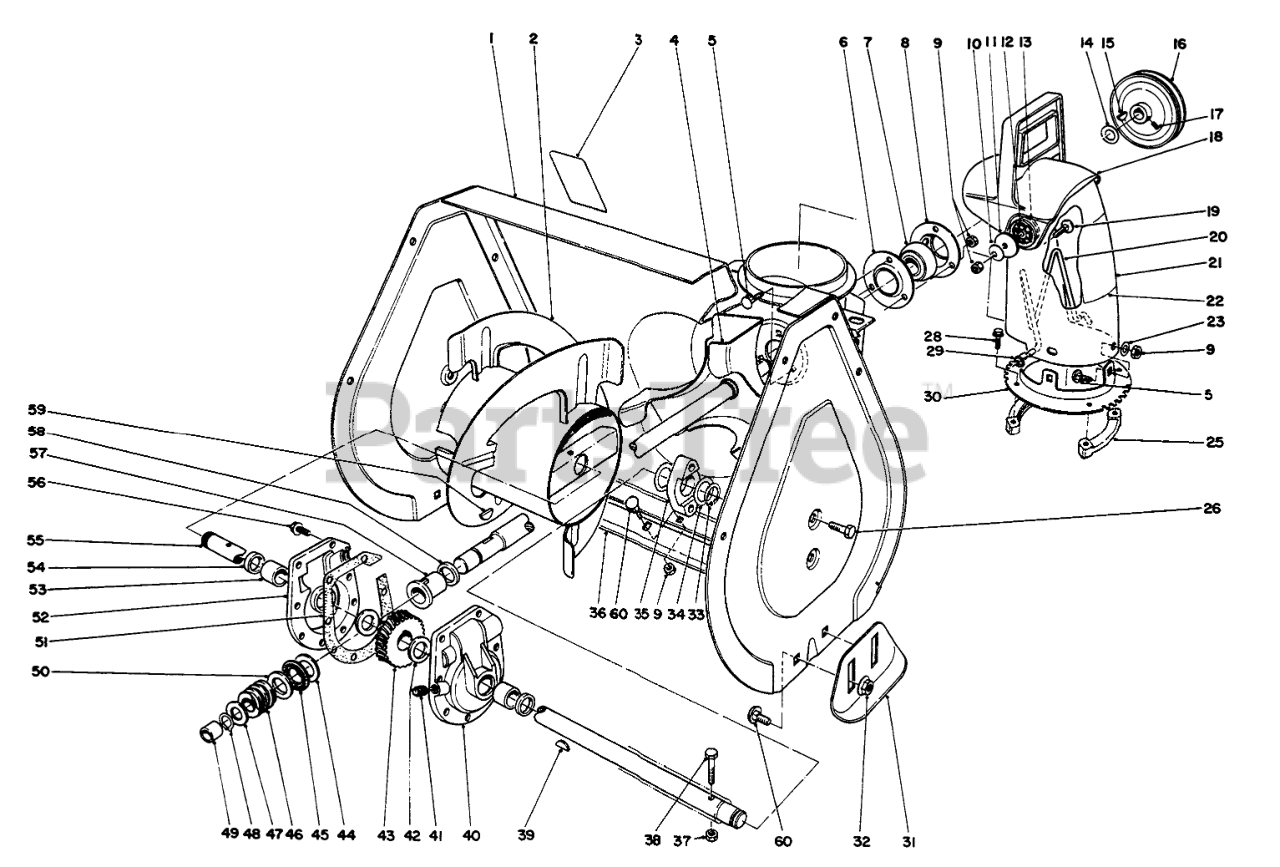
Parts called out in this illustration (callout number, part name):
1	Housing-Auger (Incl. ref. #3)
2	Auger R.H.
3	DECAL-WARNING, AUGER
4	Shaft & Impeiler
5	SCREW-CARR
6	Flange-Bearing Front
7	BEARING-BALL
8	Flange-Bearing Rear
9	NUT-LOCK, NI
10	WASHER-BELLEVILLE
11	WASHER-FLAT
12	PLATE-FRICTION
13	WASHER-RUBBER
14	WASHER
15	KEY-WOODRUFF
16	PULLEY
17	SCREW-SET, SQH
18	CHUTE-DEFLECTOR
19	SCREW-CARR
20	WIRE-CHUTE
21	Chute-Discharge (Incl. Ref. #22) Model 38052
22	Decal-Danger
23	WASHER-PLAIN
25	RING-CHUTE, RETAINER
26	SCREW-HWHTF
28	SCREW-SPECIAL
29	NUT-PUSH
30	Chute Ring
31	Skid
32	NUT-HF
33	RING-RETAINING
34	WASHER
35	BEARING-AUGER
36	Blade-Scraper
37	NUT-LOCK, NI
38	SCREW-HH
39	KEY-WOODRUFF
40	Gear Case L.H. (Incl. Ref. #53 & 54)
41	PLUG-PIPE, SQH
42	WASHER-THRUST
43	GEAR-WORM, 27T
44	WASHER-THRUST
45	BEARING-THRUST
47	WASHER-THRUST
48	Ring-Snap
49	BUSHING
50	WASHER-THRUST
51	GASKET-CASE, GEAR
52	Gear Case R.H. (Incl. Ref. #53 & 54)
53	BUSHING
54	SEAL-OIL
55	AUGER SHAFT
56	SCREW-TAPTITE
57	BUSHING-INPUT
58	RING-QUAD
59	KEY-WOODRUFF
60	BOLT-CARR
